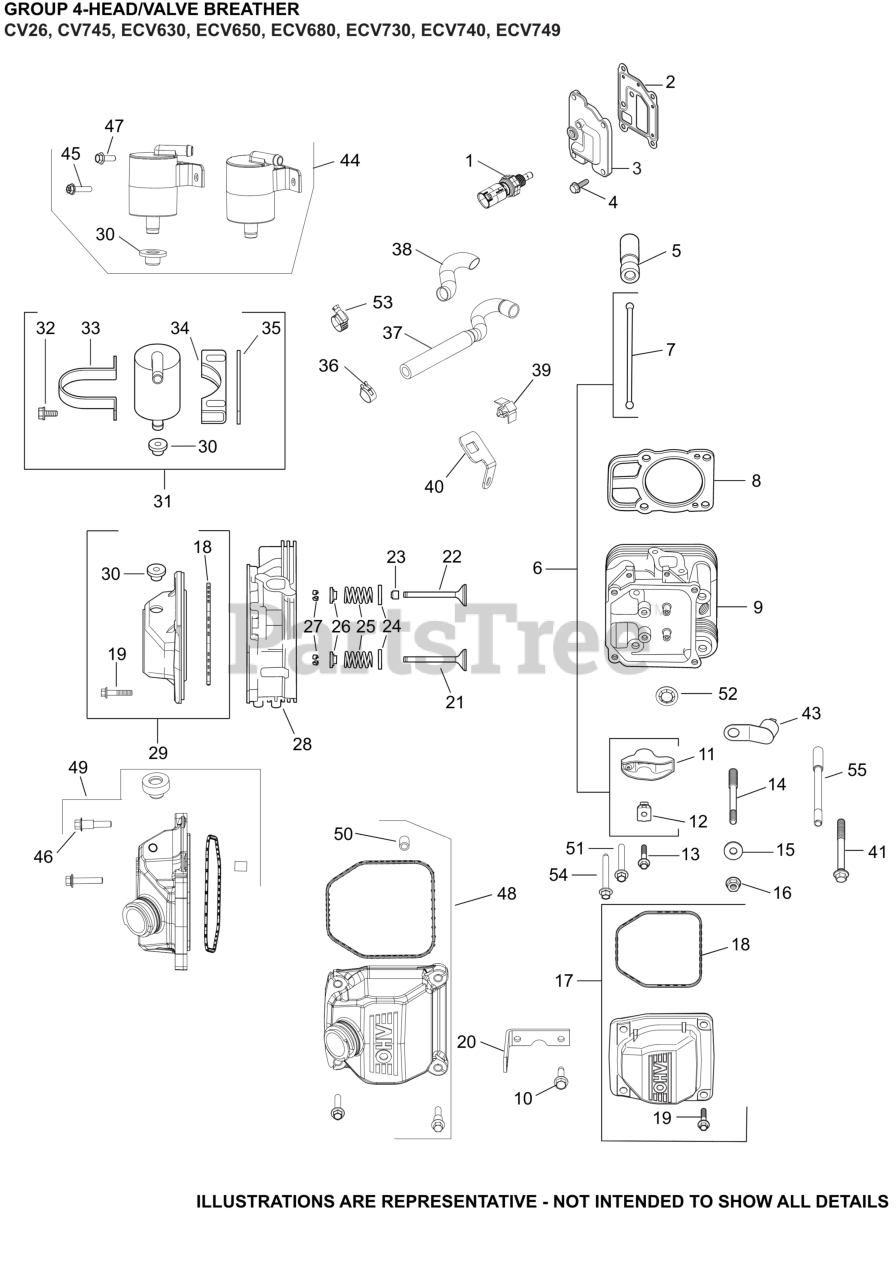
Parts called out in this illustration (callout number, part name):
1	SENSOR, TEMPERATURE
2	GASKET, BREATHER
3	KIT, BREATHER COVER
4	SCREW, THREAD FORMING
5	LIFTER, VALVE HYDRAULIC-USE 25 351 11-S
6	KIT, VALVE TRAIN
7	ROD, PUSH
8	KIT, GASKET CYLINDER HEAD
9	KIT, CYLINDER HEAD (#2)-(#2481804S)
11	ARM, ROCKER
12	PIVOT, ROCKER ARM
14	STUD, M8X1.25
15	WASHER, FLAT 8.6 MM
16	NUT, FLG M8X1.25
17	KIT, VALVE COVER-PLAIN (PLASTIC)
18	O-RING (YELLOW), VALVE CO
21	VALVE, EXHAUST
21	VALVE, EXHAUST (.25)
22	VALVE, INTAKE (STD)
22	VALVE, INTAKE (.25)-(#DSC)
23	SEAL, VALVE BAND
24	RETAINER, SPRING
25	SPRING, VALVE
26	KIT, RETAINER
27	CAP, VALVE SPRING
28	KIT, CYLINDER HEAD (#1)-(#2481803S)
29	KIT, VALVE COVER
30	GROMMET, RUBBER
37	HOSE, BREATHER
44	KIT, BREATHER SEPARATOR
47	SCREW, HI-LOW
52	RETAINER, VALVE GUIDE (KM)
54	SCREW, HEX FLANGE
NI	SCREW, HEX FLANGE (M6 X 31.625 DOG PT)
